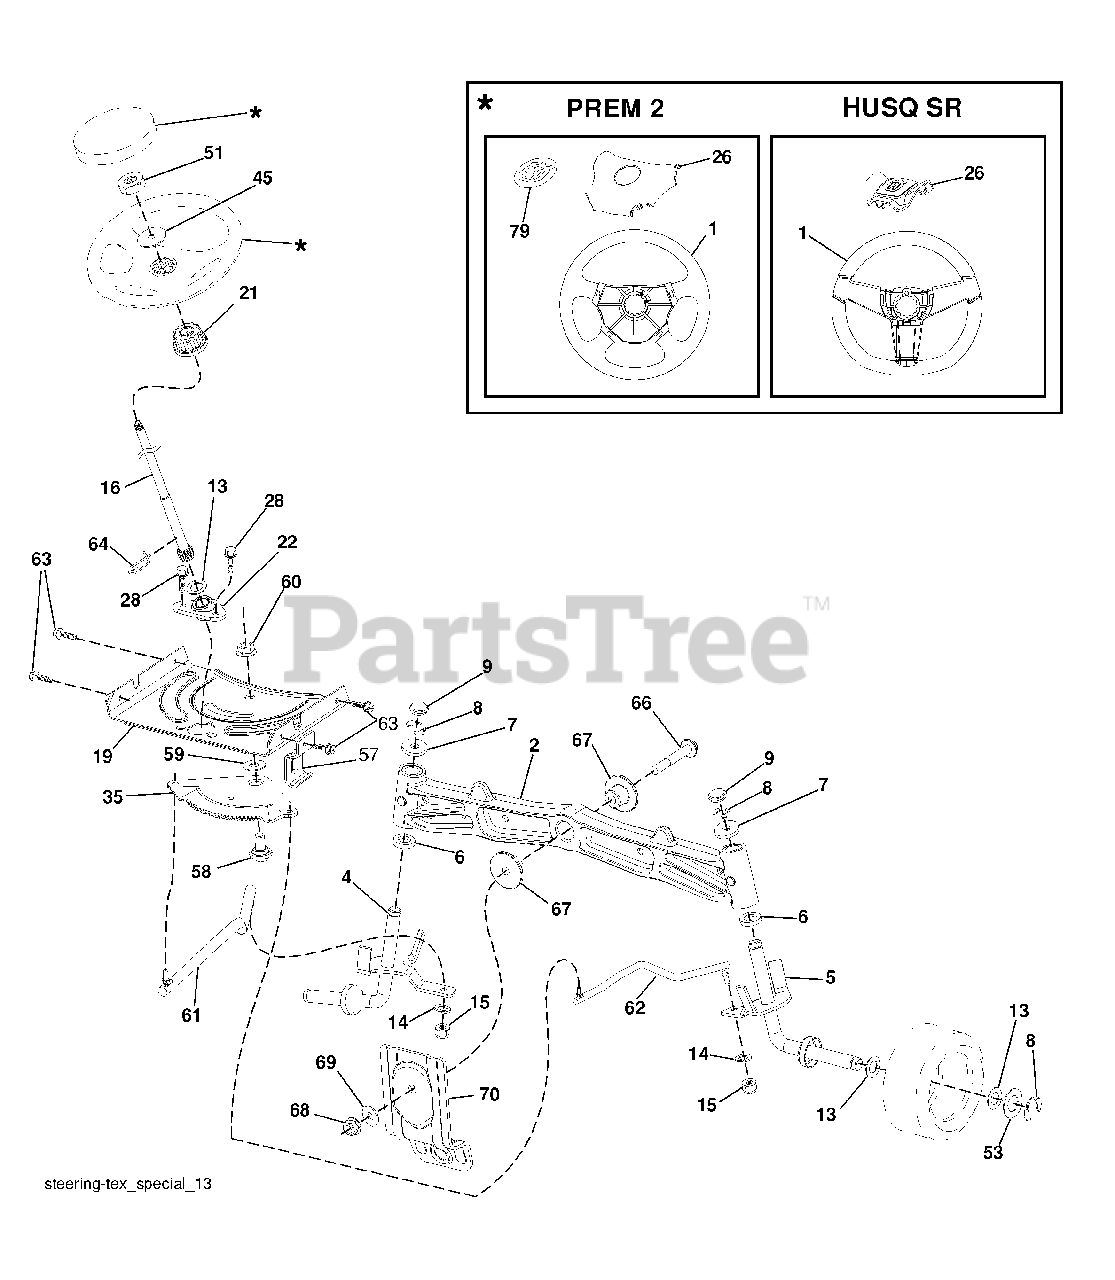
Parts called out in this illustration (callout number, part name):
1	Wheel, Steering
2	Axle Asm., Front
4	Spindle Asm., LH
5	Spindle Asm., RH
6	Bearing, Race Thrust Harden
7	Washer 25/32 x 1-5/8 x 16 Ga.
8	Ring, Klip #T5304-75
9	Cap, Spindle
13	Washer 25/32 x 1-1/4 x 16 Ga.
14	Washer, Lock Hvy Hlcl Spr 3/8
15	Nut, Crown Lock 3/8-24 unf
16	Shaft Steering
19	Plate Steering
21	Adapter, Wheel Steering
22	Bushing, Strg. Blk
26	Insert, Wheel Steering
28	Screw 3/8-16 x 3/4
35	Gear, Sector Plate
45	Washer 9/16 ID x 2-3/8 OD 12 Ga.
51	Nut Hex Jam Toplock 1/2-20 unf
53	Washer Hardened .793 x 1.637 x .060
57	Bracket Upstop
58	Bolt Shoulder Sector Pivot CFM
59	Washer Thrust Sector Steering
60	Nut Flange Lock 5/8-11
61	Draglink LH
62	Draglink, RH
63	Screw 5/16-18 x 3/4
64	Retainer Clip Spring Steering
66	Bolt Hex Fghd 7/16-14 x 3 Serr
67	Bushing PM Front Axle
68	Nut Lock Flange 7/16-14 Gr. 5
69	Washer 1.5 x .505 x .118
70	Bracket Deck Susp. Front
